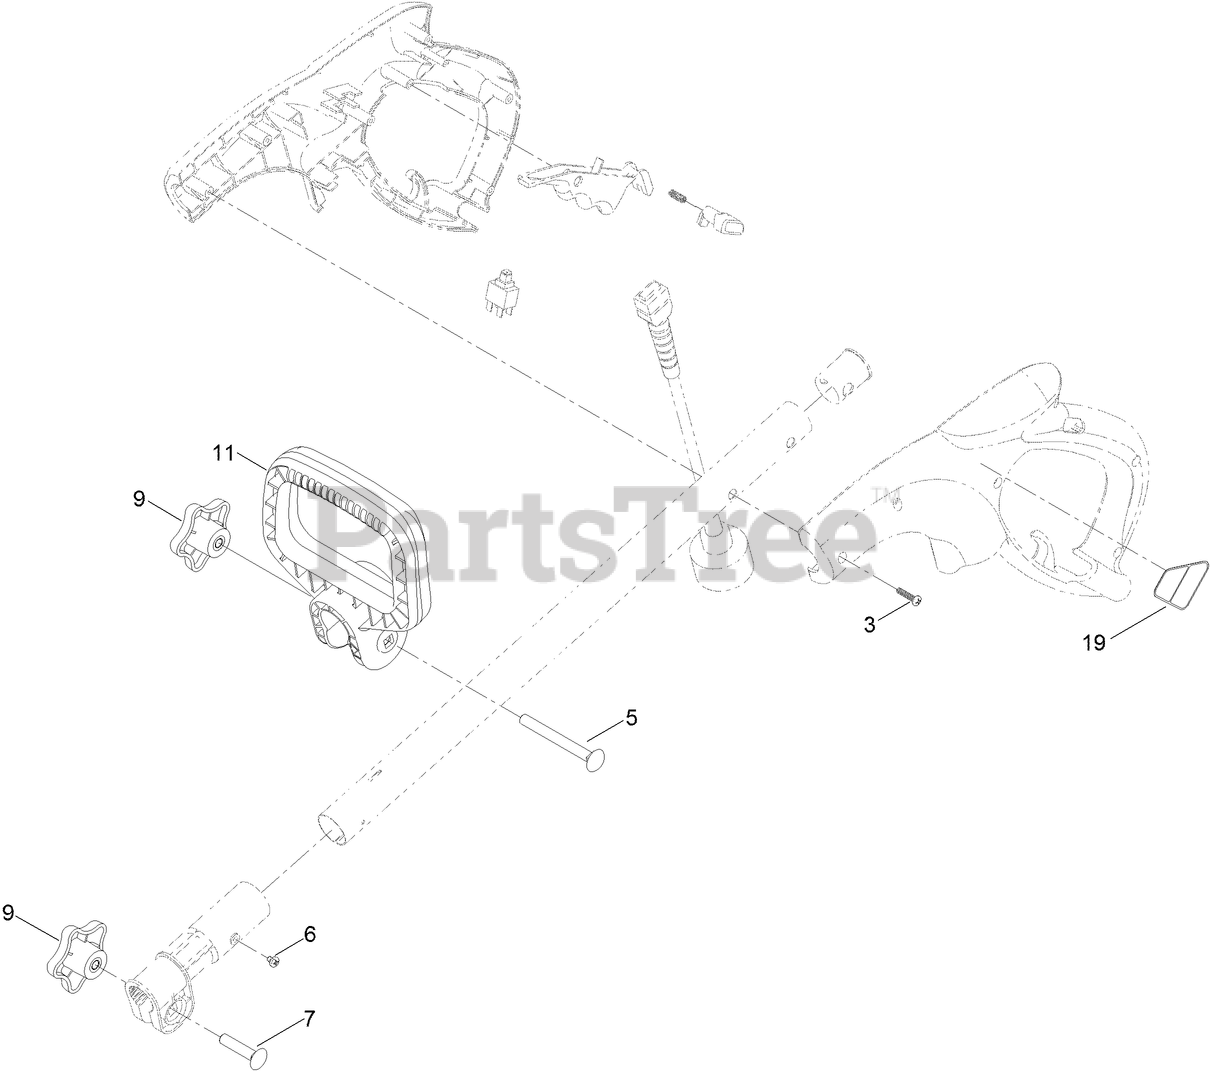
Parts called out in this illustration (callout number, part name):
3	SCREW-PPH
5	SCREW-CARR
6	SCREW-SELF TAPPING
7	BOLT-CARR
9	KNOB-HANDLE
11	HANDLE-ASSIST
19	DECAL-CONTROL
